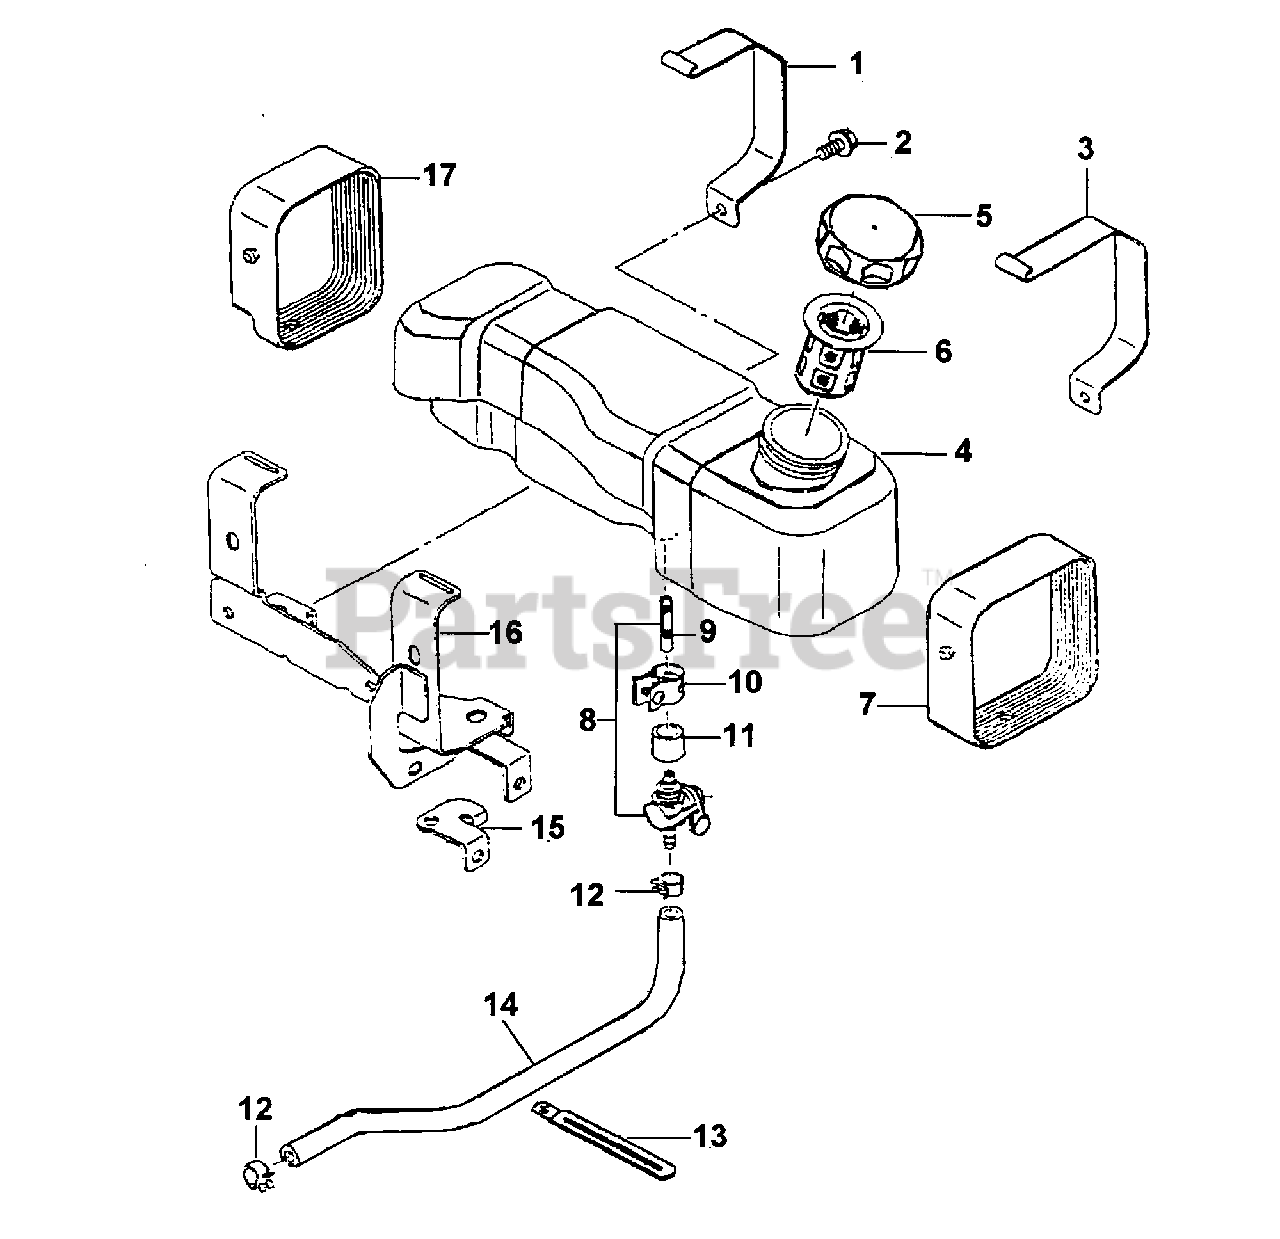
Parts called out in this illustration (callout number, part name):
1	TANK SAND 2
2	BOLT, Flange
3	TANK BAND 1
4	FUEL TANK
5	FUEL TANK CAP
6	FILTER, Fuel
8	FUEL STRAINER
10	BAND, Hose
11	JOINT PIPE
12	CLAMP, Hose
14	RUBBER PIPE
15	BRACKET, Fuel Tank
16	BRACKET, Fuel Tank
